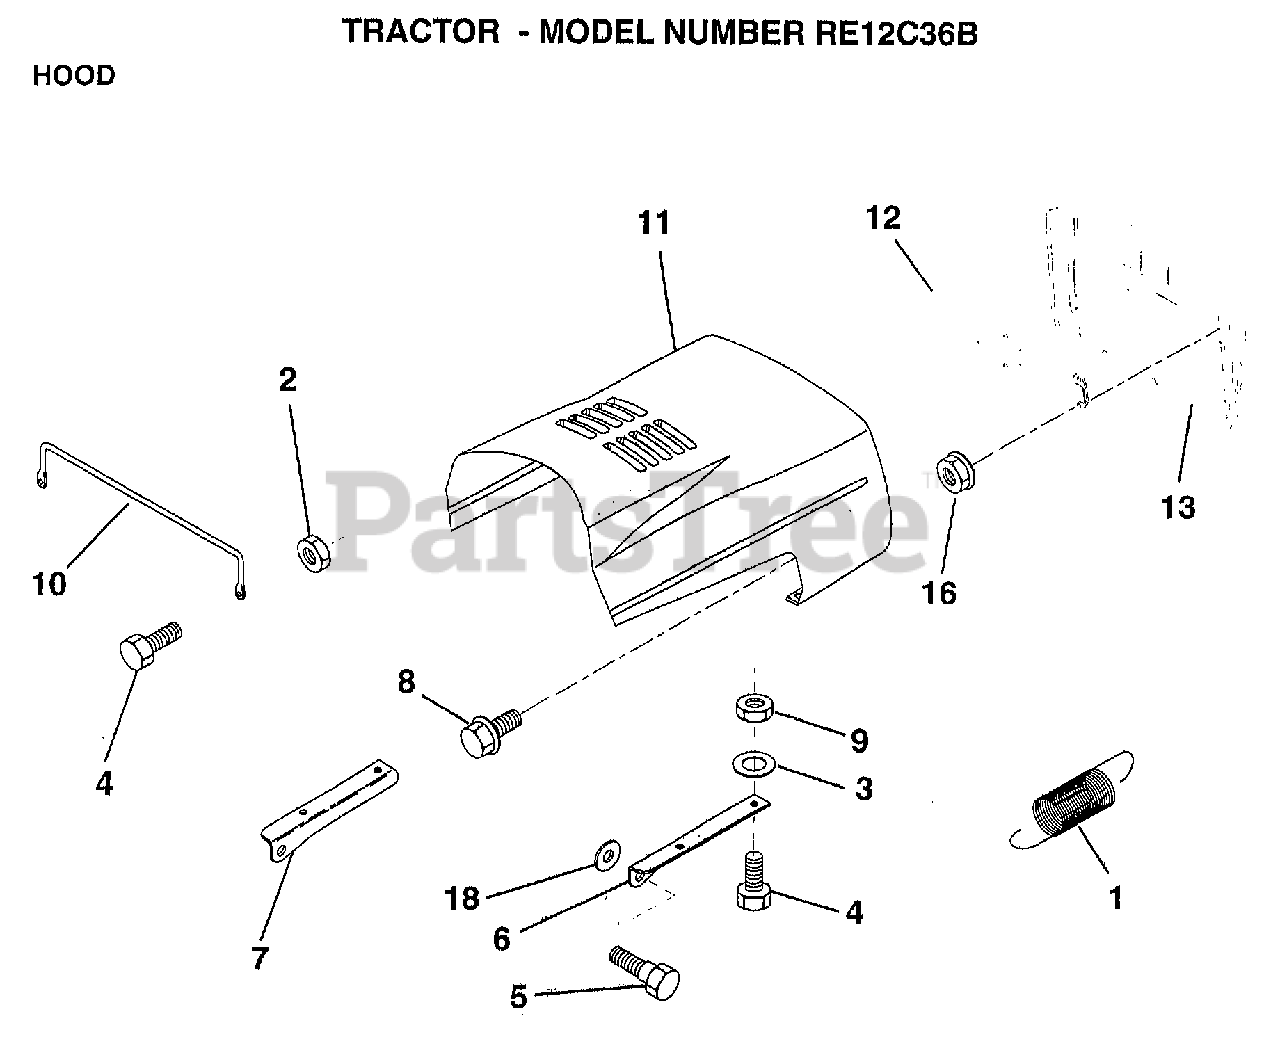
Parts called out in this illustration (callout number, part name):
1	EXT SPRING
2	NUT
3	WASHER
5	BOLT.SHLD.5/16-18
6	BRKT HOOD RH
7	BRKT HOOD LH
8	"SCREW,HWHD.HI-LO#13-16X3/4"
9	NUT
10	"BRACE,HOOD"
11	HOOD
13	GRILL (BLACK)
16	NUT
18	WASHER
